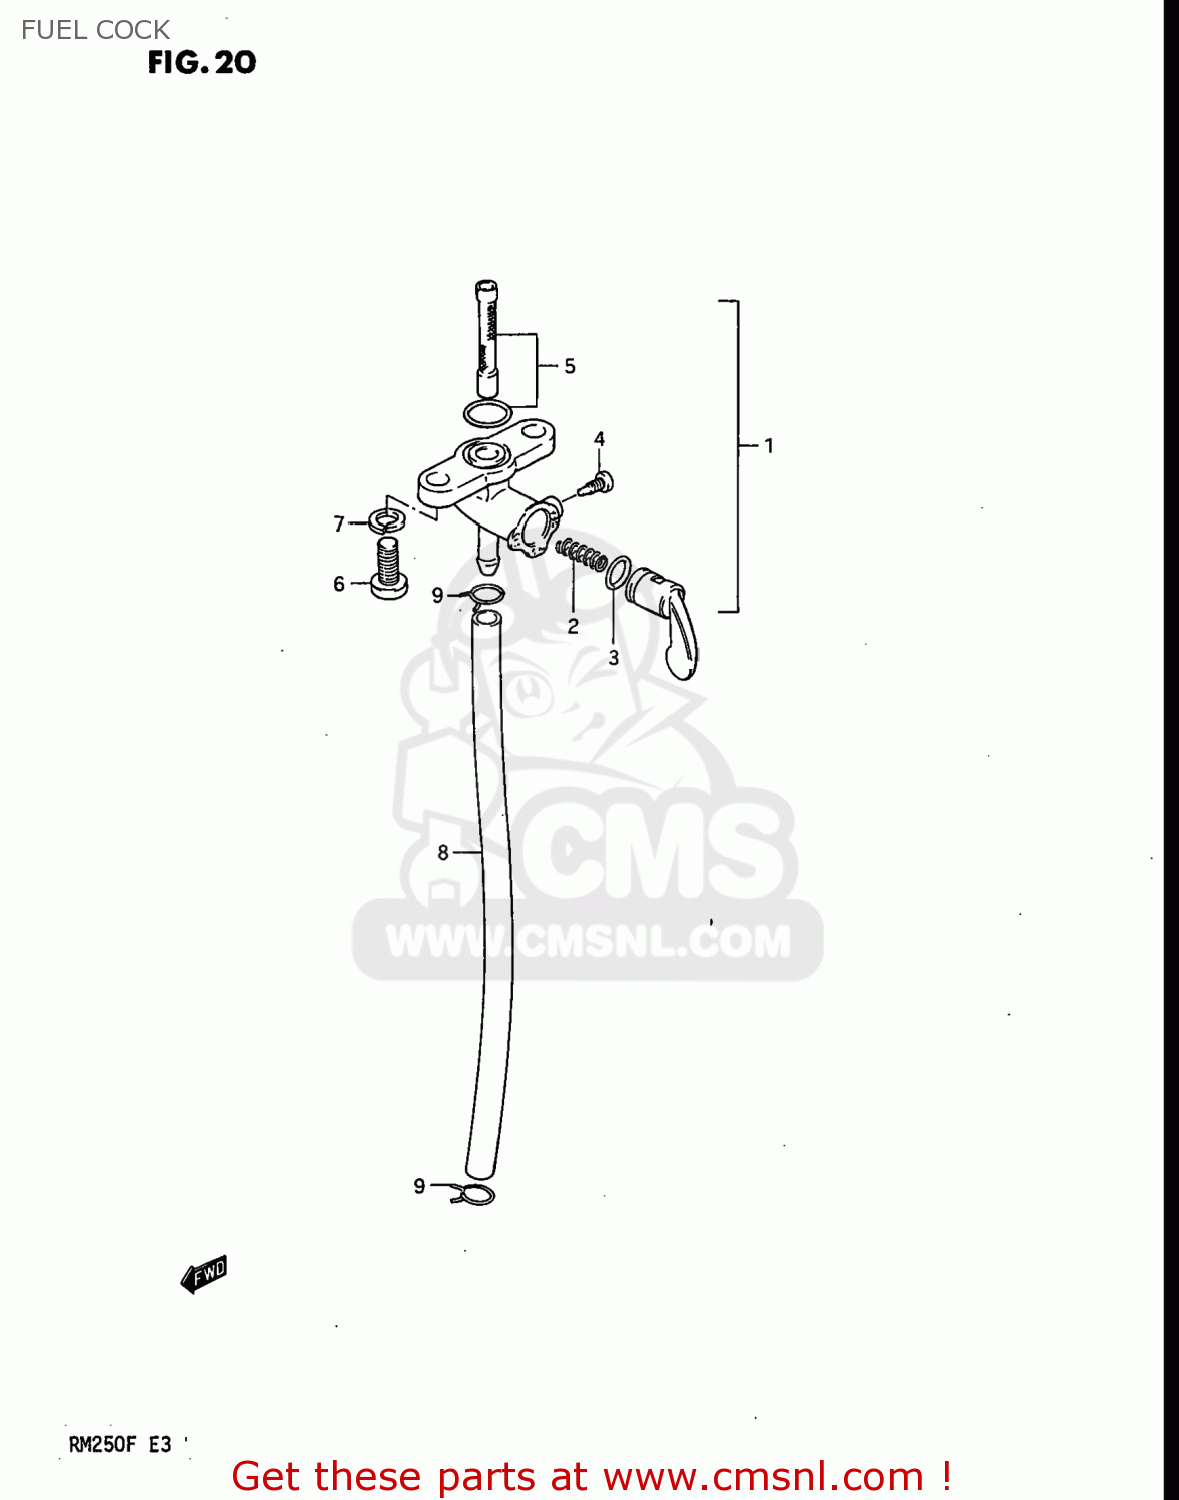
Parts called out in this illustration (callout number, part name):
1	COCK ASSY,FUEL
2	SPRING,FUEL COCK VALUE
3	O RING,LEVER
4	SCREW
5	FILTER SET FUEL
6	SCREW
7	LOCK WASHER
8	HOSE,FUEL
9	CLAMP
